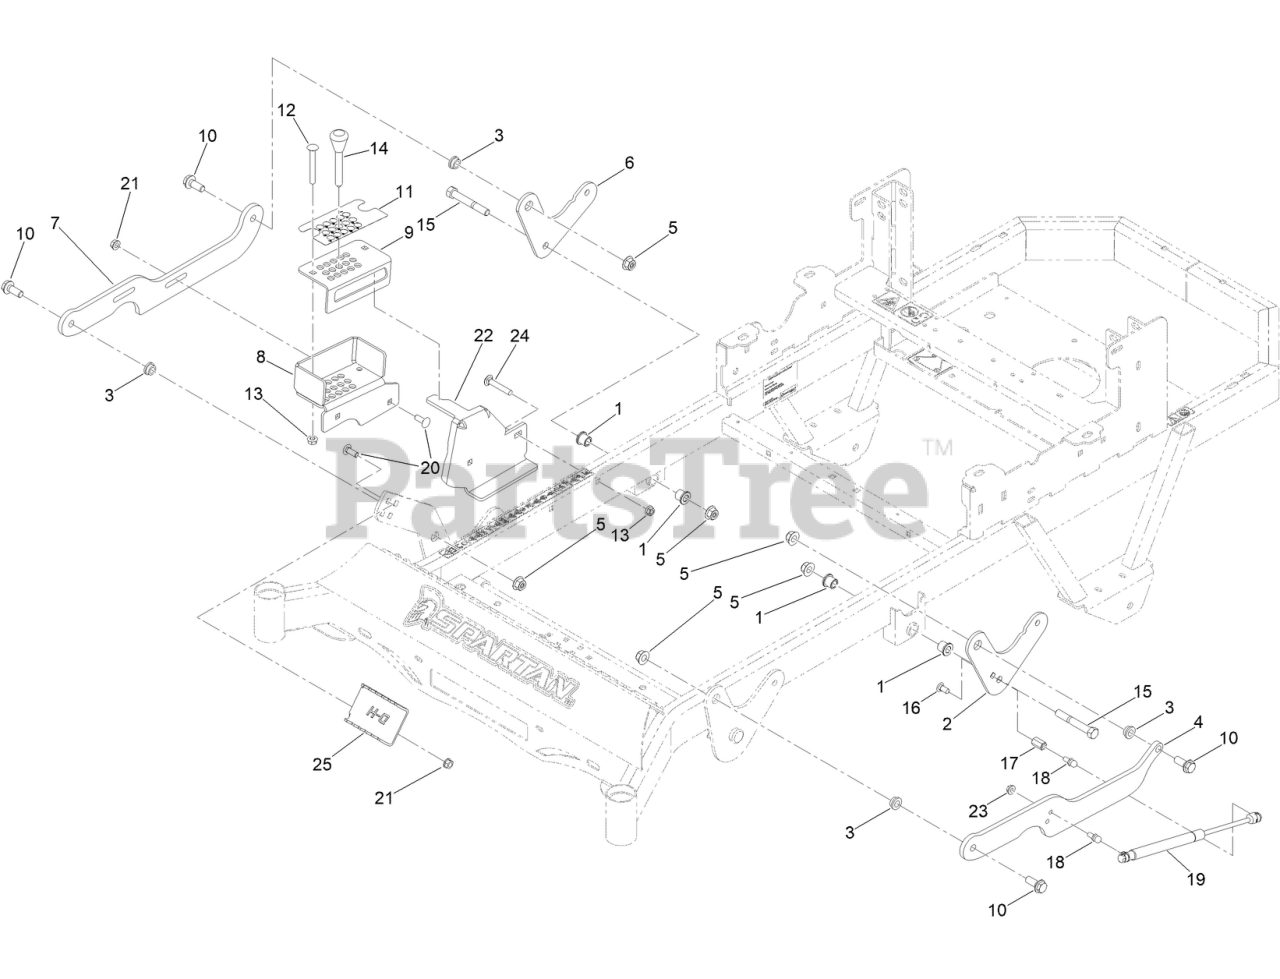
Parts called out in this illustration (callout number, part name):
1	BUSHING-FLANGE
2	ARM-DECKLIFT REAR (1/4")
3	1/2IN ID X 3/4IN OD X 3/8IN FLANGE BUSH
4	LINK-DECKLIFT
5	1/2-13 HEX FLANGE 2-WAY REV CNTR L/NYZ
6	ARM-DECKLIFT REAR (1/4")
7	2024 DECK HEIGHT ARM RT LINK
8	BRACKET PIN SYSTEM (BOTTOM) PAINTED GREY
9	2022 DHI PIN ARM LINK TOP BRKT
10	1/2-13X1.25IN HEX FLANGE BOLT (GR.8) YZ
11	DECAL-HEIGHT OF CUT
12	(3/8-16 X 3 CARRIAGE BOLT (GR.5) ZC/YEL)
14	MAGNETIC PIN FOR STAND ON MWR
15	1/2-13 X 3-1/2 HEX C/S GR 5 ZINC YELLOW
16	3/8 X 3/4IN GR 8 CARR BOLT ZINC
17	HEX COUPLING NUT - REDUCER (3/8" TO 5/16
18	5/16-18X1.286 DAMPER BALL STUD (.562 TL)
19	RZ DECK ASSIST GAS SPRING
20	SCREW-CARR
21	NUT-HHF, WHIZ
22	2022 DECK LOCK PIN TUBE BRKT
23	NUT-HF
24	SCREW-CARR
25	MWR DECK HEIGHT FOOT PEDAL PAINT
